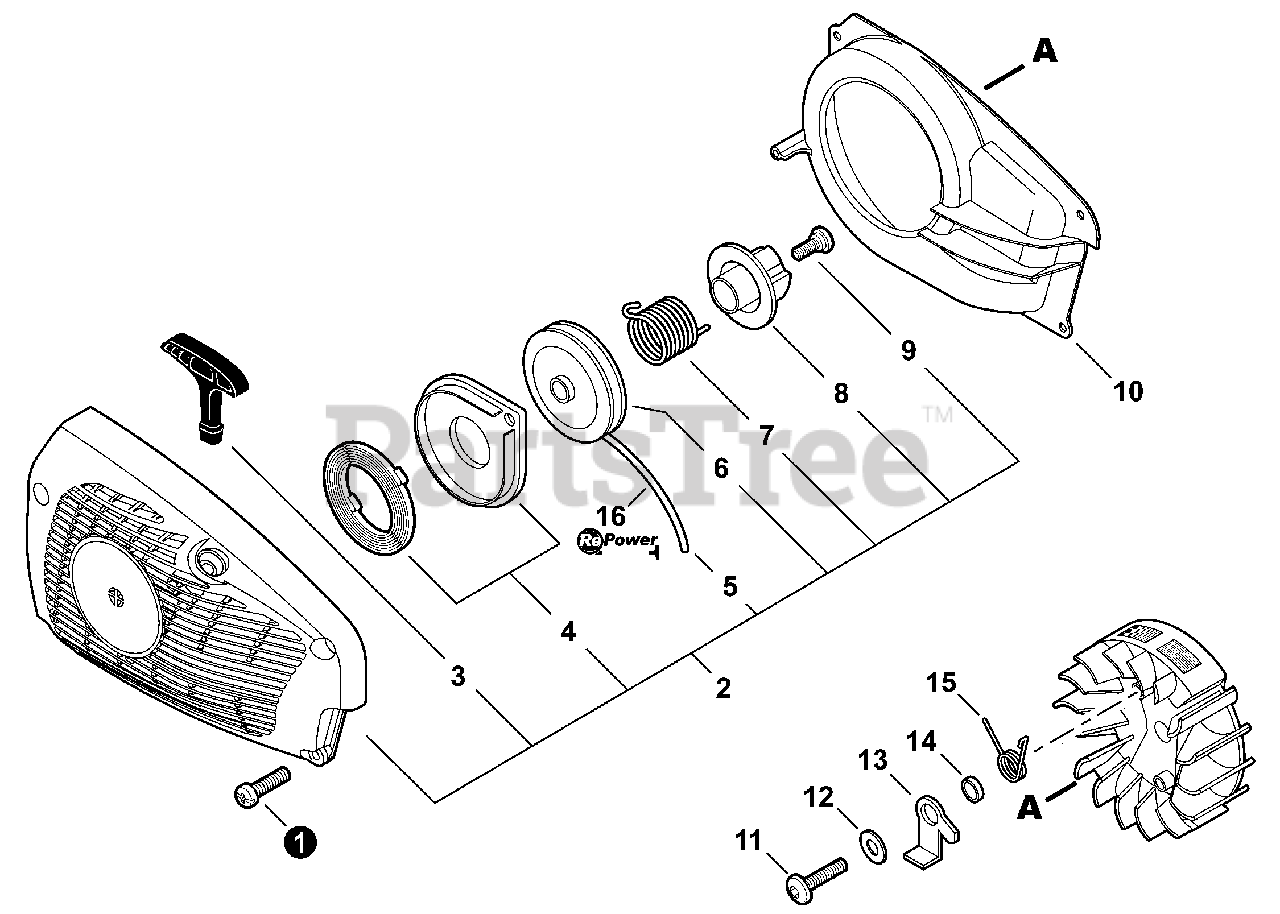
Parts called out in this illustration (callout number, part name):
1	BOLT, TORX 4×16
2	STARTER ASSY, RECOIL
3	GRIP, STARTER
4	SPRING KIT, RECOIL
5	ROPE, STARTER 3.5×900
6	REEL, ROPE
7	SPRING, RETURN
8	PLATE, CAM
9	SCREW
10	COVER, FAN
11	BOLT 5×14
12	WASHER 5.5×12×0.8
13	PAWL, STARTER
14	SPACER 5.2×8×2.1
15	SPRING, TORSION
16	ROPE, STARTER - REPOWER BULK
